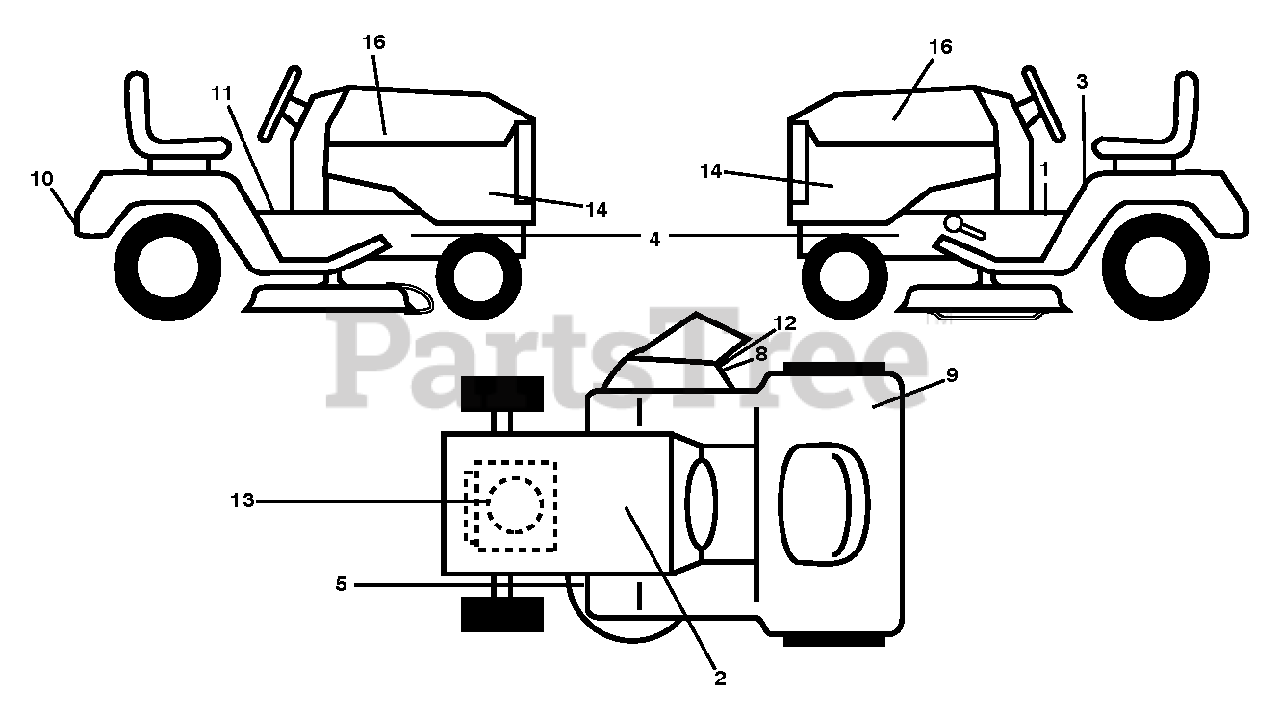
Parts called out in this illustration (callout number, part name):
1	DECAL.PARKING.BRAKE.SADDLE.LT
2	DECAL BTRY SYMBOLS
3	DECAL.READ.OWN.MAN.SYMBOL.LT
4	DECAL.CHASSIS.HOT.MUFFLER
5	DECAL.V-BELT.SCH.42/46"MEC/ELE
8	DECAL.DFLCTR.WARNNG.CTFNGR.SYM
9	DECAL.PEDALS.SYMBOL
10	DECAL.CHASSIS.6MIL.DRAWBAR
11	DECAL.FNDR.SDLE.BRAKE.CLUTCH.6
12	DECAL.CUTFINGER.CE.02
13	DECAL.ENGINE.WARNING
14	DECAL TRACTOR SIDE PANEL DECAL
16	DECAL.BADGE.170MM.TEXTLOGO.
